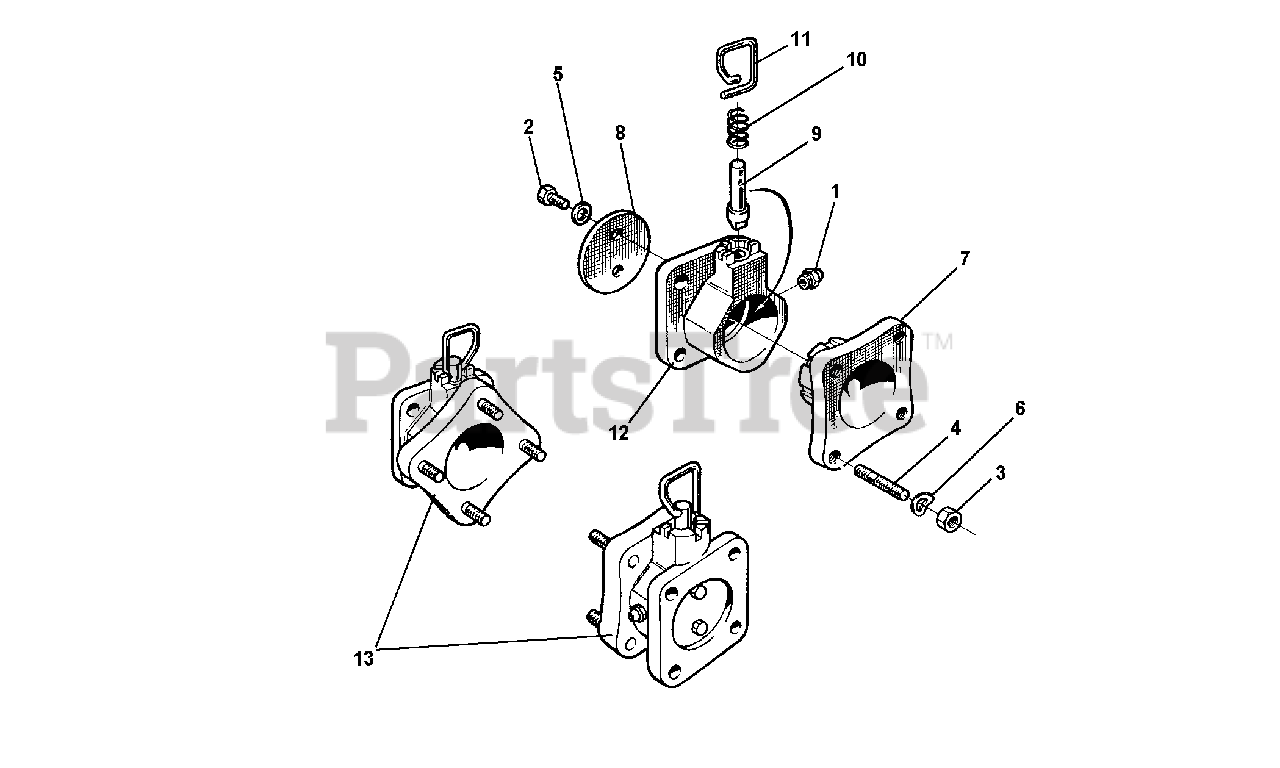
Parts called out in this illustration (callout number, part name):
1	LUBRICATOR M10
2	SCREW M8 X 14
4	STUD M10 X 40 X 22 X 14
5	WASHER, LOCK 8.4
6	WASHER, LOCK 10.5
7	GROOVED HUB
11	RETAINING RING
12	HUB COMPLETE
13	FREE WHEEL DEVICES (PR)
